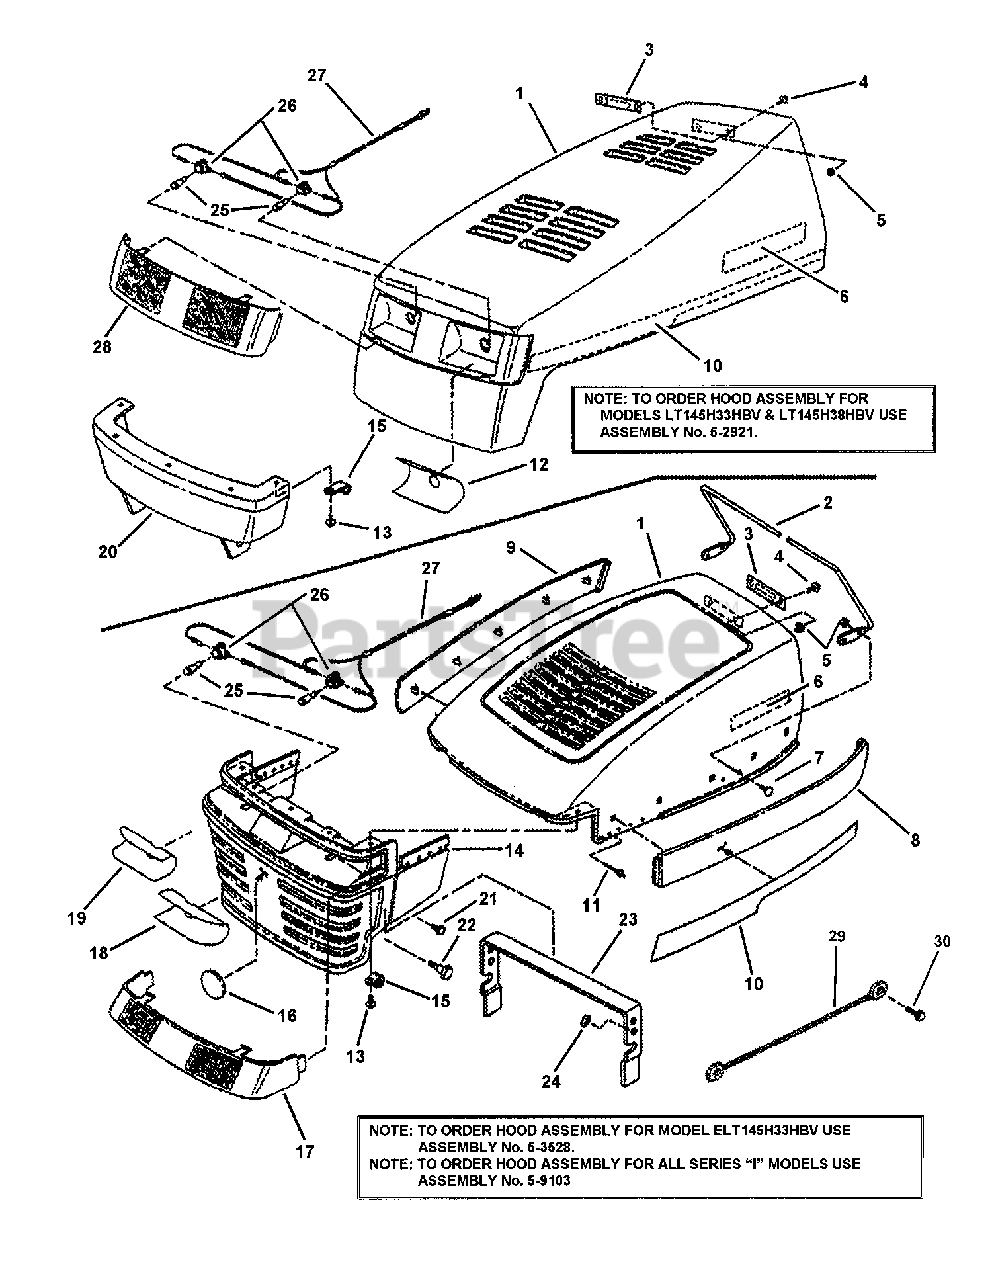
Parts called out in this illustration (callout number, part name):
1	HOOD
1	HOOD, Mozart
1	HOOD, Mozart-Scoop-Red
2	ROD, Hood Support
3	CLIP, Spring-Latch
4	SCREW, 1/4-20 x 5/8 Pan Head Self-Tap (Torx)
5	NUT, 1/4-20 Hex Nyloc
6	DECAL, Snapper- Hood- 3D Silver Letters
7	BOLT, 1/4-20 x 5/8" Flat Head Square Neck, GR 5
8	PANEL, Hood, Left Hand, Black
9	PANEL, Hood, Right Hand, Black
10	DECAL, Hood "LE1433H", Right Hand
10	DECAL, Hood "LE1433H", Left Hand
10	DECAL, Hood "LE14538H", Right Hand
10	DECAL, Hood "LE14538H", Left Hand
10	DECAL, Hood "LE1538H", Right Hand
10	DECAL, Hood "LE1538H", Left Hand
10	DECAL, Hood "LT1533H", Right Hand
10	DECAL, Hood "LT1533H", Left Hand
10	DECAL, Hood "LT1538H", Right Hand
10	DECAL, Hood "LT1538H", Left Hand
10	DECAL, Hood "LT1833H", Right Hand
10	DECAL, Hood "LT1833H", Left Hand
10	DECAL, Hood "LT1838H", Right Hand
10	DECAL, Hood "LT1838H", Left Hand
11	POP RIVET, 1/8 x 3/8"
12	DECAL, Clear Lens, Left Hand
12	DECAL, Clear Lens, Right Hand
13	SCREW, M4.8 x 1.59 x 16mm HXCRHD Sems Special
14	GRILL, Sloped, Black
15	CLIP, "J" Open Type .4 Bundle Dia., .281 Dia. Hole
16	DECAL, Molded Medallion
17	LENS, Rippled, Sloped
18	DECAL, Lens/Reflector-LH Sloped Grill
19	DECAL, Lens/Reflector-RH Sloped Grill
20	BUMPER, Front Hood Support
21	SCREW, 5/16-18 x 1/2" Hex Washer Self-Tap
22	SHOULDER BOLT, 3/8-16 x 1-1/4" Hex Socket
23	BRACE. Hood Support/Stop
24	RETAINER, 5/16" Bolt
25	LAMP 1141, Headlight
26	SOCKET, Headlight Snap-In
27	HARNESS, Headlight M&G Sockets
28	LENS, Clear (Models with Headlights)
29	LANYARD, Hood, 14-3/4" long
30	SCREW, 1/4-20 x 1-1/4" Hex Head Cap w/Locking Patch
